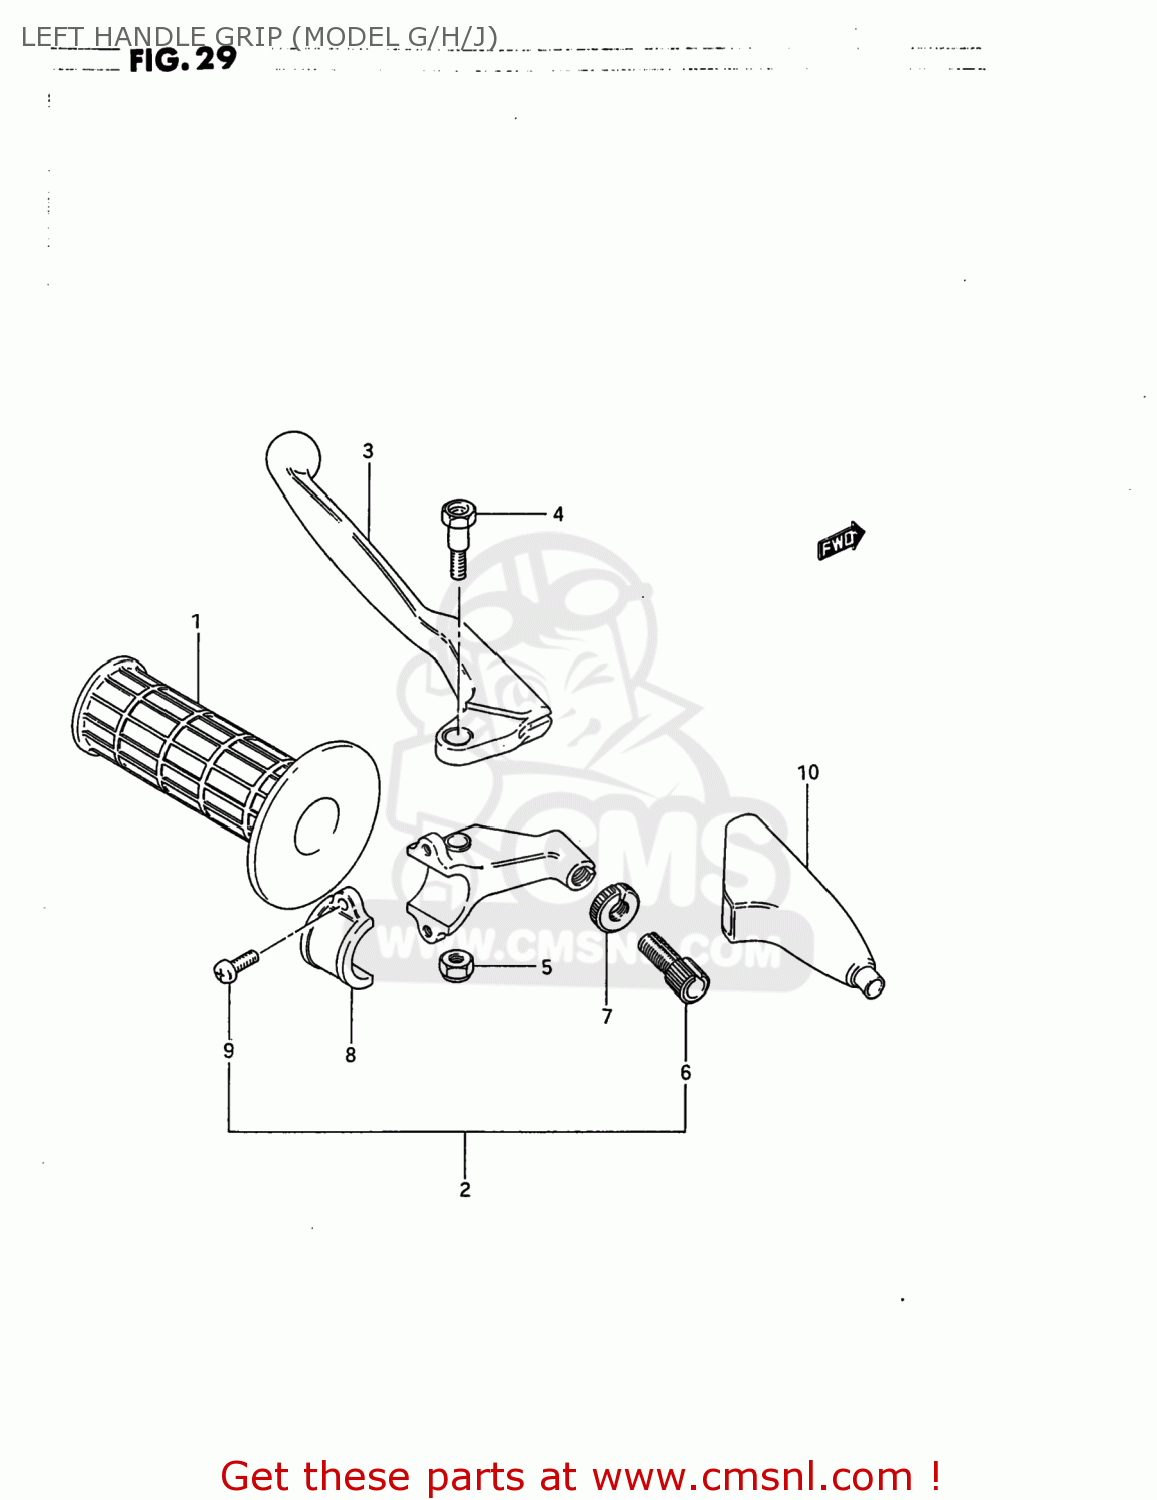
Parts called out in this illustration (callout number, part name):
1	GRIP,LEFT
2	LEVER ASSEMBLY
3	LEVER,CLUTCH
4	BOLT,LEVER
5	NUT
6	ADJUSTER,CABLE
7	NUT,CABLE ADJUSTER LOCK
8	HOLDER,LEVER
9	SCREW (5X14)
10	COVER,CLUTCH LEVER
